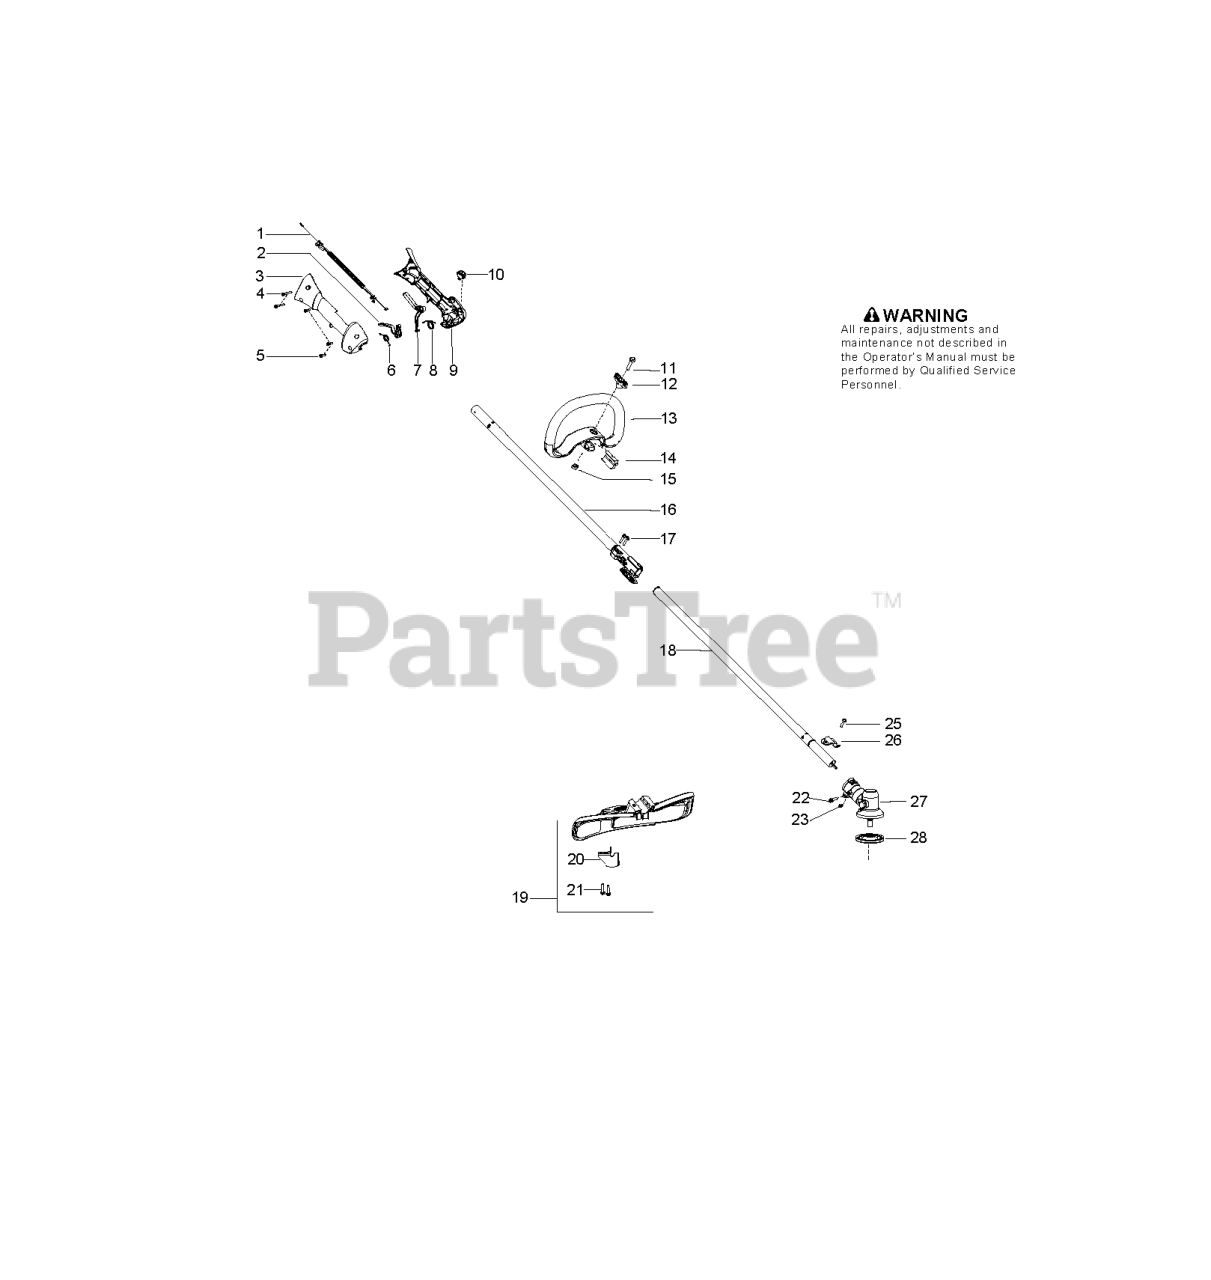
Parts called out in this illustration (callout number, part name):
1	ASSY-CABLE WIRE HARNESS
2	TRIGGER THROTTLE
3	HOUSING-THROTTLE RH
5	SCREW M4 X 1.75 PT 16MM
6	SPRING TRIGGER
7	THROTTLE LOCKOUT
8	SPRING LOCKOUT
9	HSG THROTTLE LH
10	KIT SWITCH
16	DRIVE SHAFT
18	KIT DRIVESHAFT LOWER LDX
19	KIT COBI SHIELD
20	Limiter - Line
22	SCREW - CARB. ADAPTOR
25	SCREW 1/4-20 X 7/8 (TAP
26	BRACKET SHIELD STRAIGHT SHAFT
27	ASSY GEARBOX
28	DRIVE DISC
